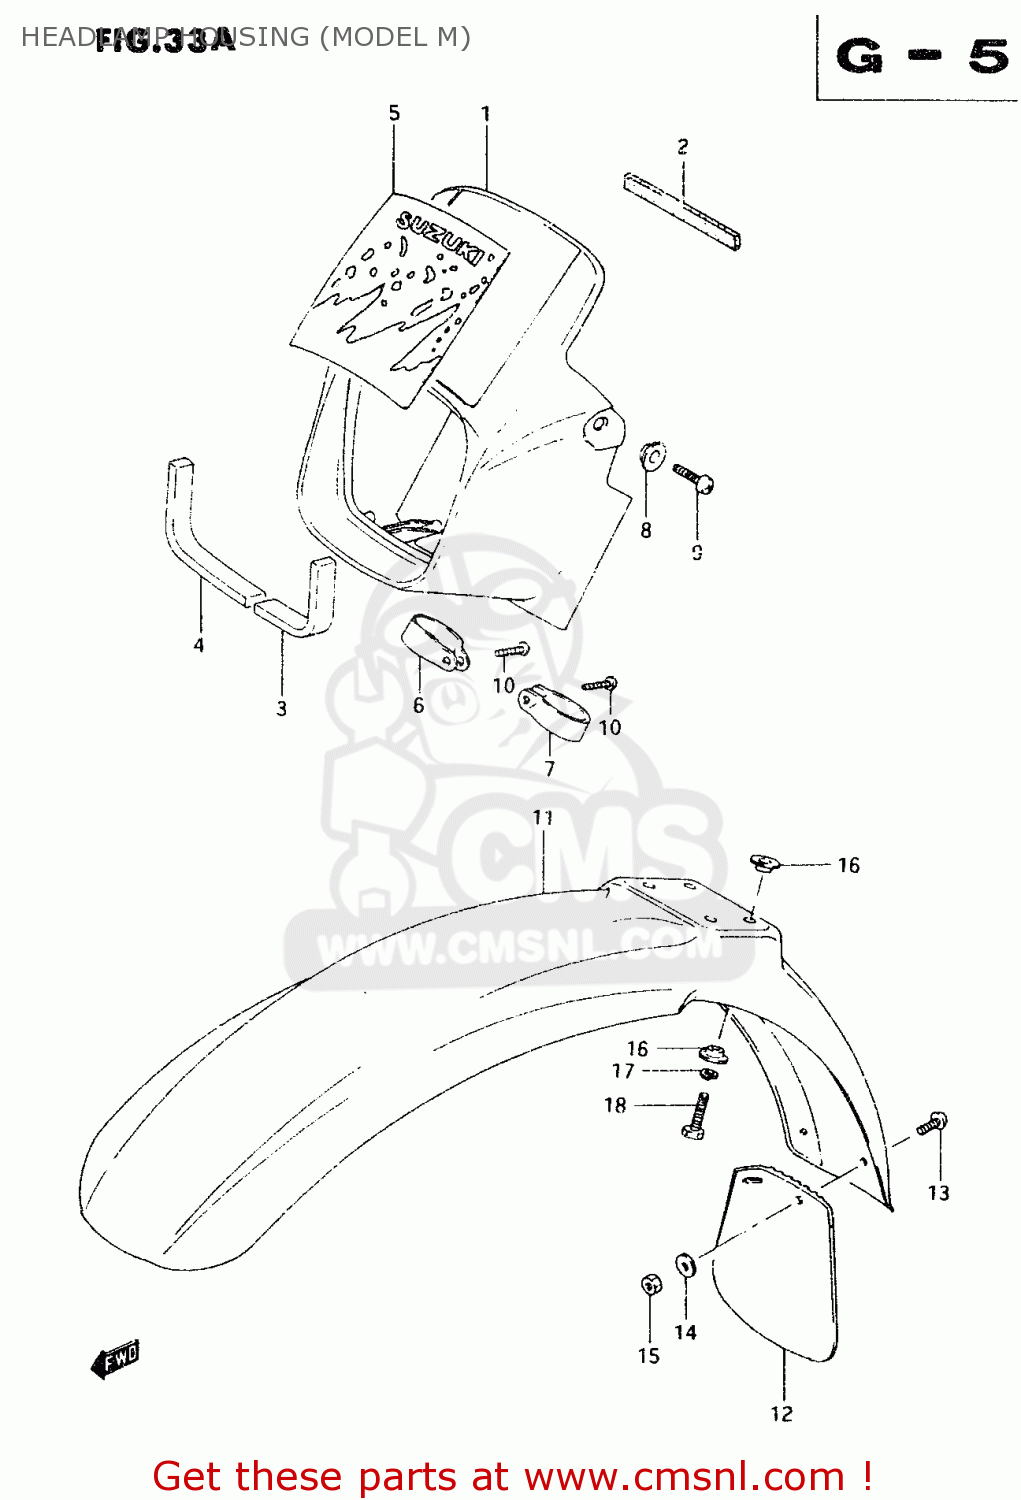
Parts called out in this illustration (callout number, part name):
1	HOUSING,HEADLAMP
2	CUSHION,HEADLAMP HOUSING
3	CUSHION,HEADL.
4	CUSHION,HEAD L
5	TAPE, HEADLAMP COVER
6	CLAMP,HEADLAMP HOUSING,R
7	CLAMP, HEADLAMP HOUSING, LH
8	WASHER
9	SCREW
10	SCREW
11	FENDER,FR
12	MUD FLAP,FRONT FENDER
13	SCREW
14	WASHER
15	NUT
16	WASHER
17	WASHER,LOCK
18	BOLT
